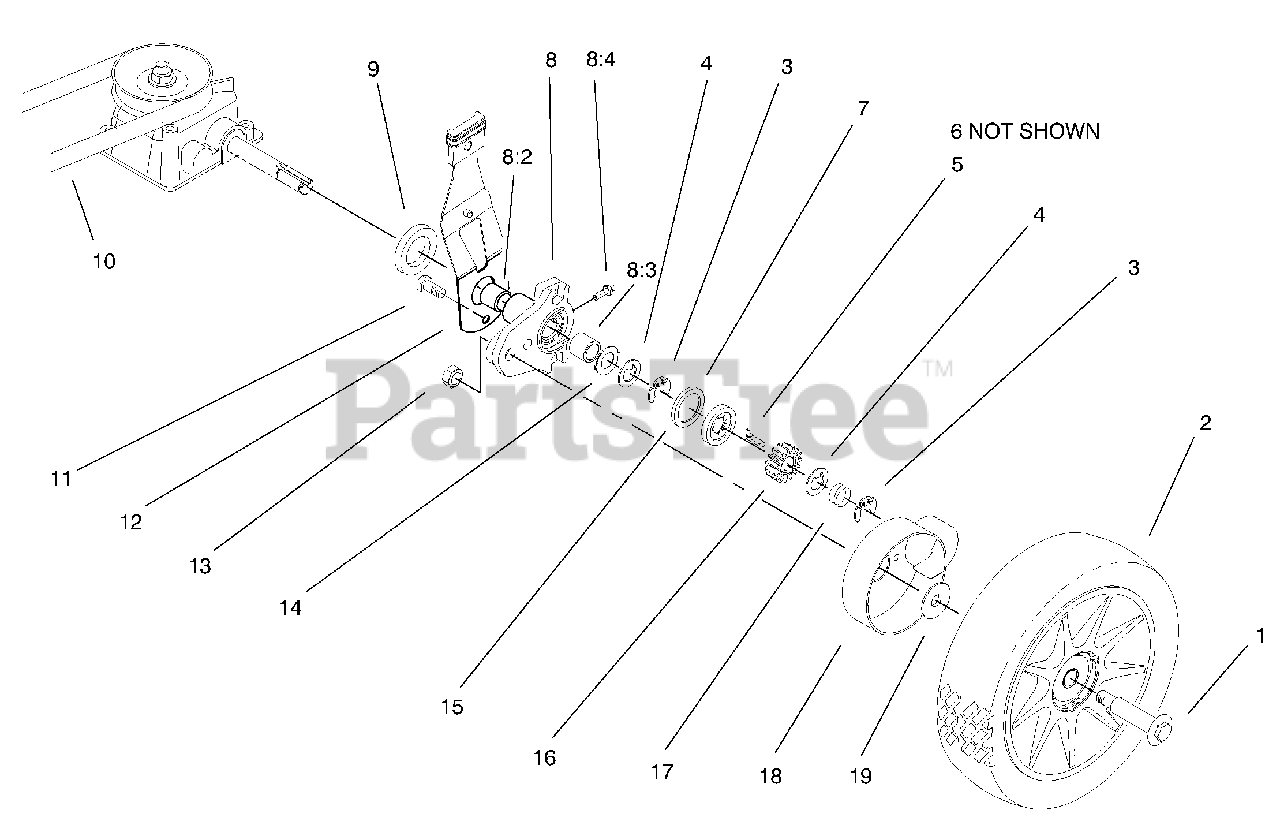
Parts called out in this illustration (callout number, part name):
1	Bolt-Shoulder
3	Ring-Retaining
4	Washer-Thrust
5	Key-Rocking LH
6	Key-Locking RH
7	Ring-Friction
8	ASM-Hgt Adj Arm
8:4	Fitting-Grease
9	Spacer-Axle Shaft
12	ASM-Spring Arm
13	Nut-Lock
14	Washer-Thrust
16	Gear-Pinion
17	Spring-Compression
18	Cover-Wheel
19	Washer-Stepped
